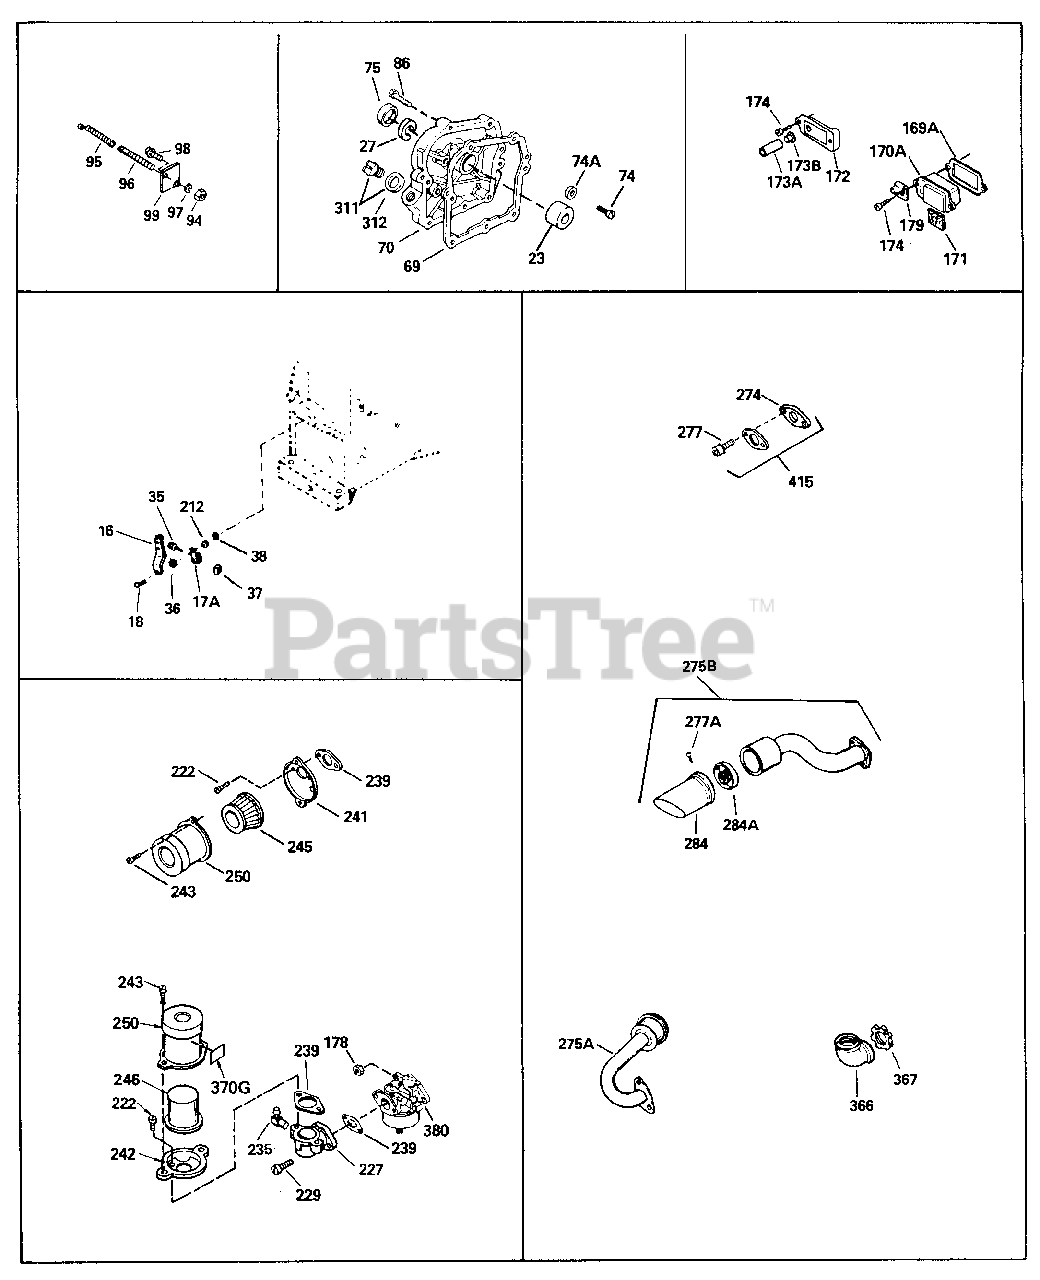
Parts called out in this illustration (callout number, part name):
16	Lever, Governor
18	Screw, 8-32 x 5/16"
69	* Gasket, Cylinder cover
70	Cover, Cylinder (Incl. 75, 76 & 80)
75	Oil Seal
86	Screw, 1/4-20 x 1-1/4"
171	Element, Breather
172	Cover, Breather
174	Screw, 10-24 x 1/2"
178	Nut & Lock Washer 1/4-28
222	Screw, 10-32 x 1/2"
274	* Gasket, Exhaust
277	Screw, 1/4-20 x 2-1/2"
380	Carburetor (Incl. 184) (Refer to Divi sion 5, Section A, page 168 for break down)
415	Muffler Adapter Kit (Incl. 64 & 274) As req.
999	Winter Maintenance Kit incl. 5W30 Oil , Spark Plug, Key, & Ultra-Fresh
999	Winter Maintenance Kit (incl. 0W30 Sy nthetic Oil, Spark Plug, Key, & Ultra -Fresh)
